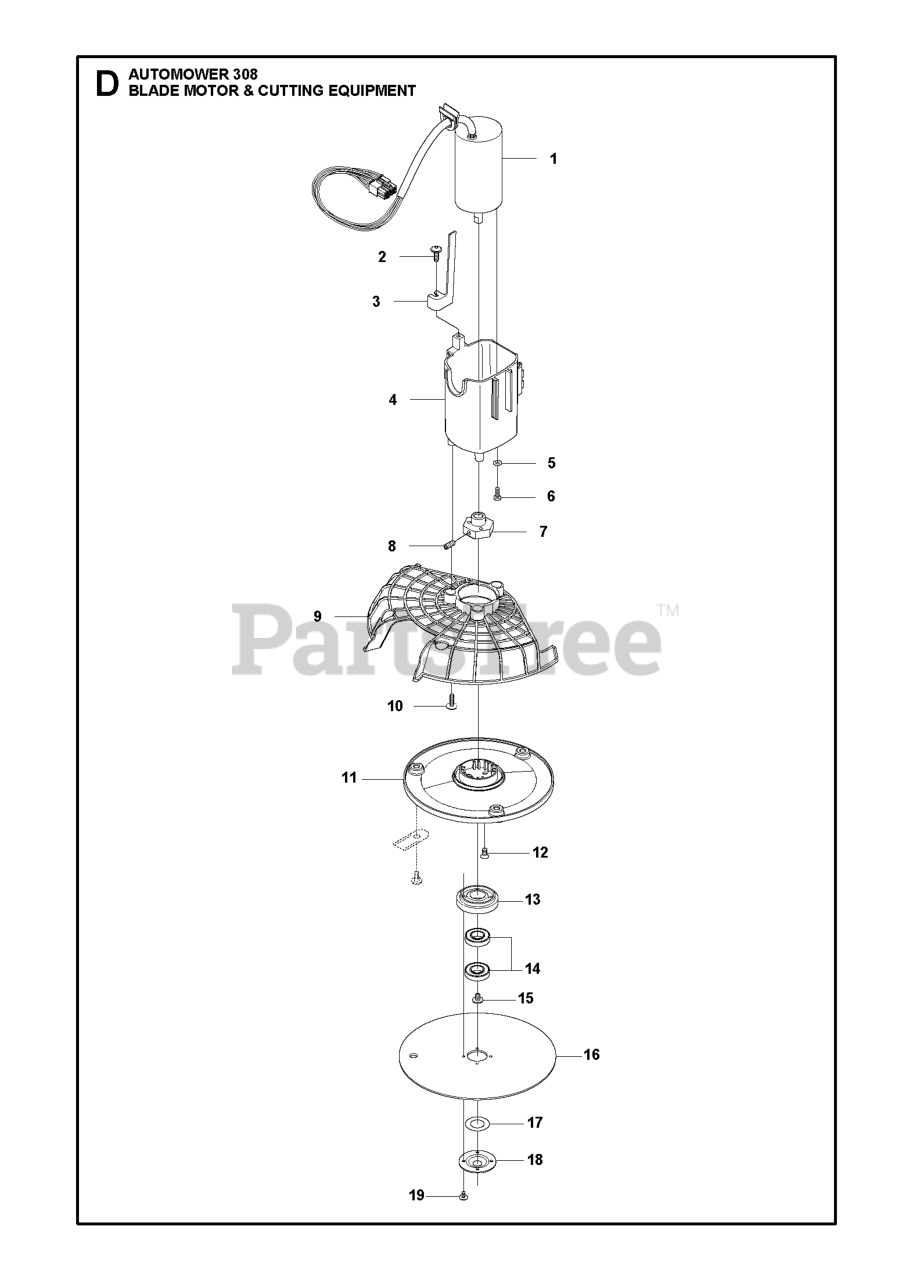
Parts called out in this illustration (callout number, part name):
2	SCREW 14MM
3	HEIGHT INDICATOR
4	MOTOR HOUSING
6	SCREW ITXPANM M4X12 8.8 ZP-BC
8	SCREW IHSETM M5X10 8.8 ZP-BC
10	SCREW 14MM
12	SCREW
14	BALL BEARING BALL BEARING 535
18	COVER SKID PLATE
19	SCREW SILVER 10MM
